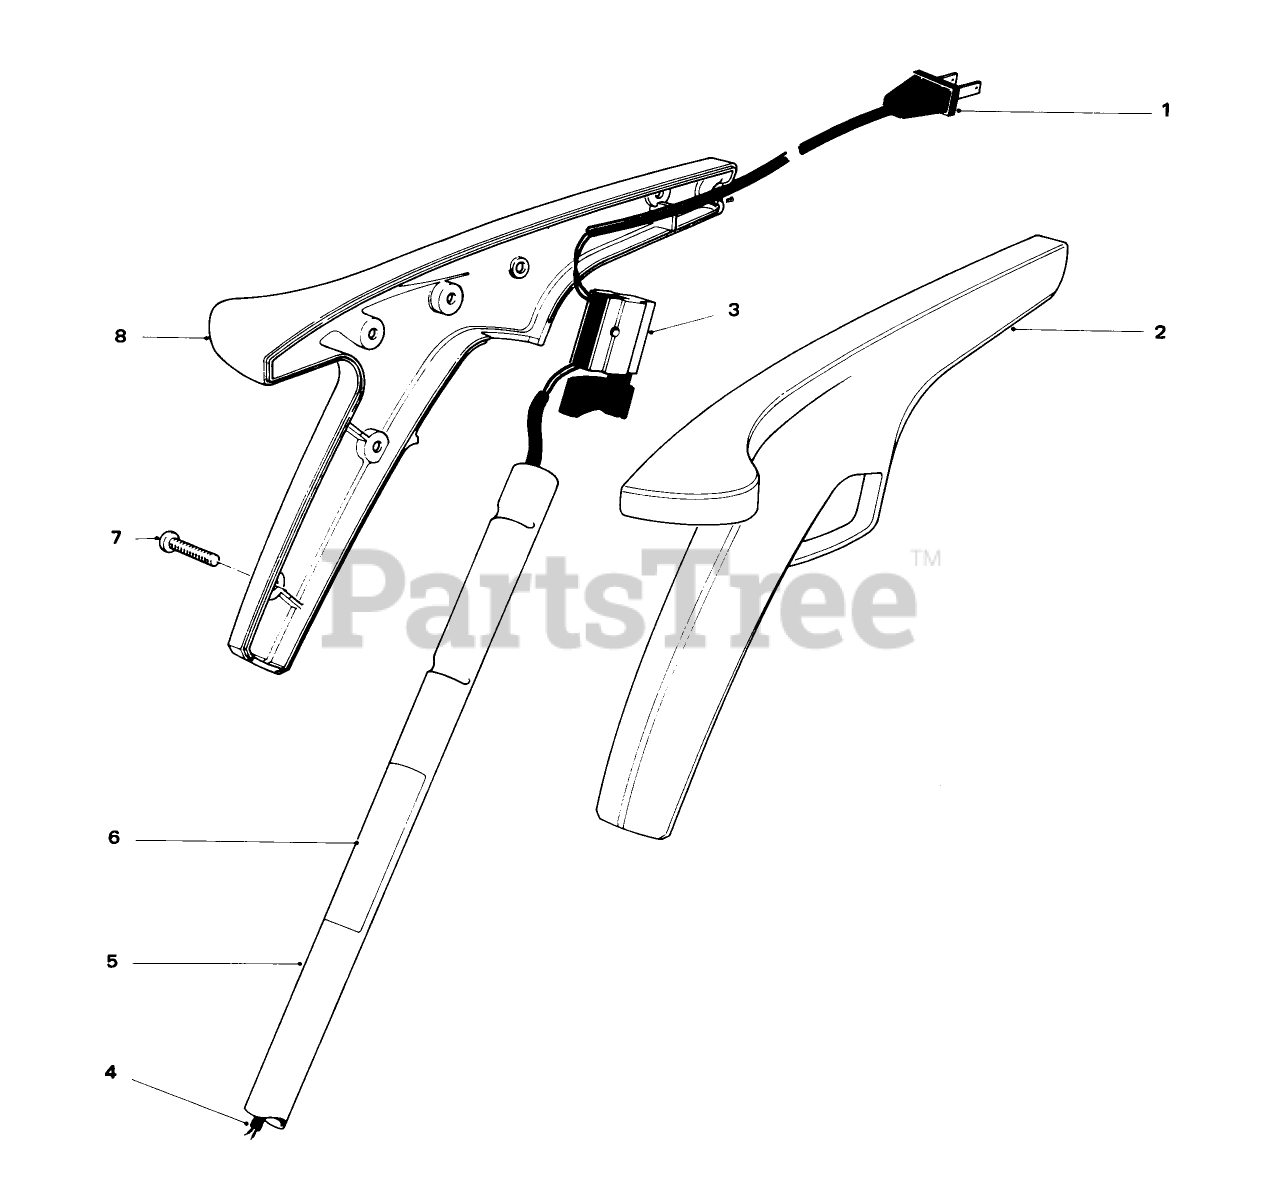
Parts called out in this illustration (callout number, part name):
1	Power Cord
2	LH HANDLE GRIP
3	SWITCH SINGLE SPEED
4	Wiring Harness
6	REPLACEMNT SERIAL PLT
7	Screw
8	Grip-Right Hand
